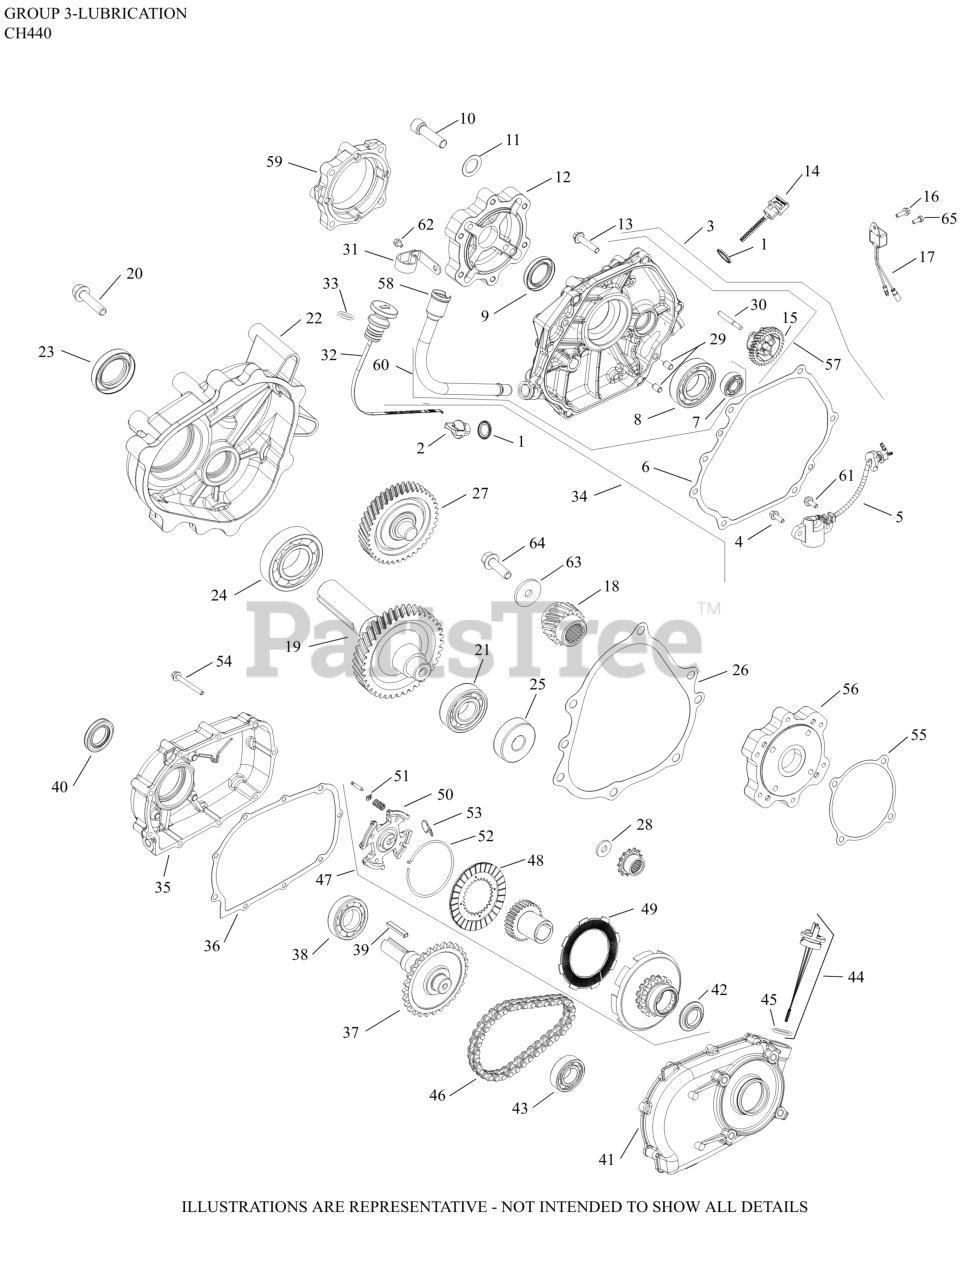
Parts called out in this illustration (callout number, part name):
1	GASKET, DIPSTICK
4	SCREW, M6 X18
5	SWITCH, OIL SENSOR ASSEMBLY
6	GASKET, CLOSURE PLATE
8	BEARING, BALL
13	SCREW, CLOSURE PLATE
14	DIPSTICK ASSEMBLY
15	GOVERNOR ASSEMBLY
16	SCREW, HEX/PHILLIPS M5
17	CONTROL, OIL ALERT UNIT
30	SHAFT, GOVERNOR GEAR
57	KIT, CLOSURE PLATE
61	SCREW, M6 X 16
66	DIPSTICK - USE 17 038 08-S
